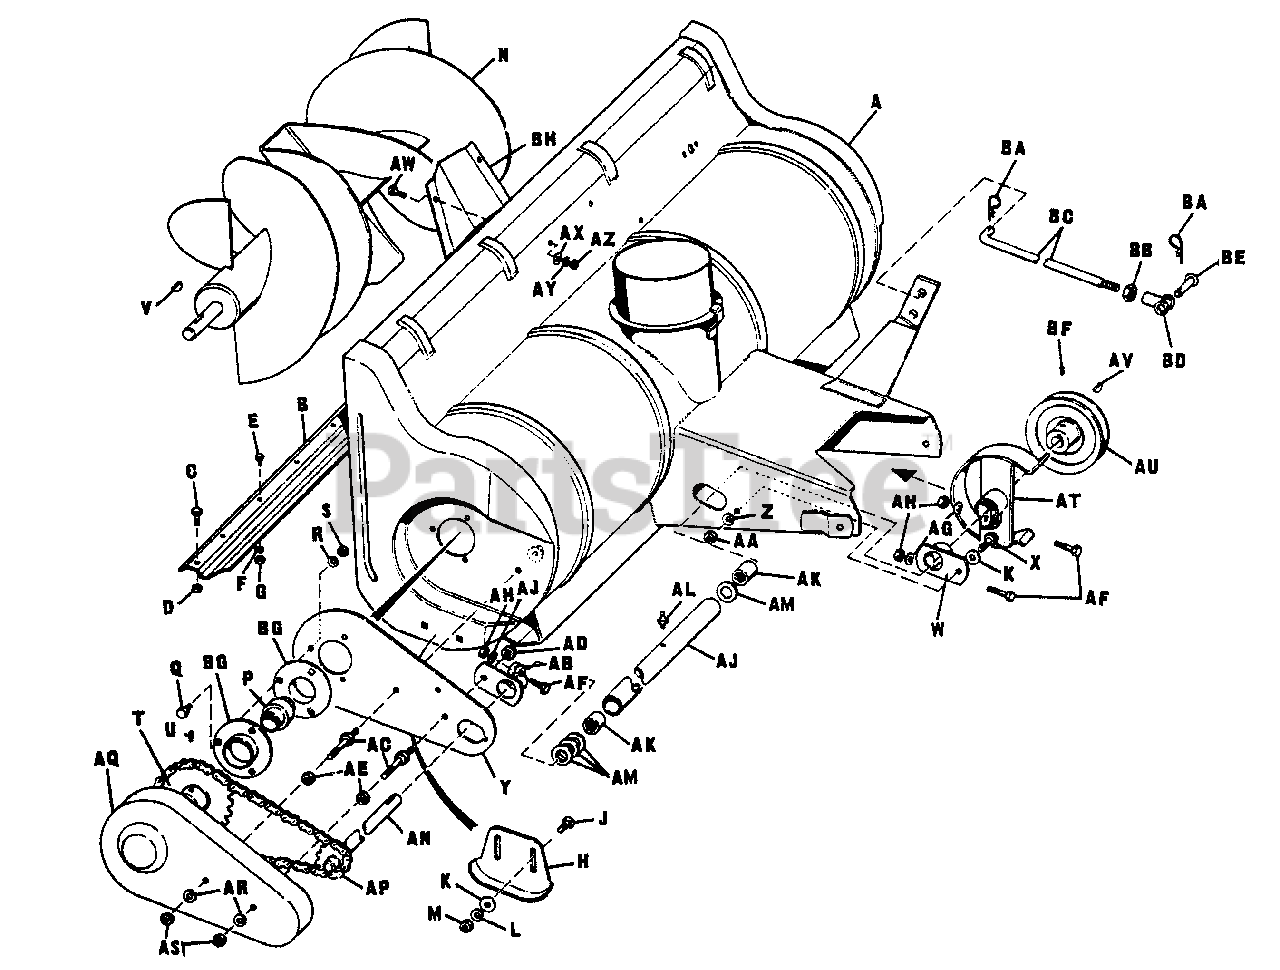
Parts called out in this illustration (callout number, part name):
A	Body Assembly
B	Body Scraper
C	Hex. Cap Screw,5/16"-18 x 5/8"
D	Full Lock Hex. Nut, 5/16"-18
E	Hex. Cap Screw, 1/4"-20 x 5/8"
F	Lock Washer, 1/4"
G	Full Hex. Nut, 1/4"-20
J	Carriage Bolt, 3/8"-16 x 3/4"
K	Plain Washer, 3/8"
L	Lock Washer, 3/8"
M	Full Hex. Nut, 3/8"-16
N	Rotor Assembly
P	Bearing Cartridge
Q	Hex. Cap Screw, 5/16"-18 x 3/4"
R	Lock Washer, 5/16"
S	Full Hex. Nut, 5/16"-18
T	Rotor Sprocket
U	Set Screw, 5/16"-18 x 5/16"
W	Support Assembly Clamp
X	Hex. Can Screw, 3/8"-1 x 1"
Y	Side Plate
Z	Lock Washer, 3/8"
AA	Full Hex. Nut 3/8"-16
AB	Support Assembly Clamp
AD	Nut, Flange, 3/8"-16
AE	Full Lock Hex., 3/8"-16
AF	Hex. Cap Screw, 5/16"-18 x 1-1/2"
AG	Lock Washer, 5/16"
AH	Full Hex. Nut, 5/16"-18
AJ	Bearing Housing
AK	Needle Bearing
AL	Grease Fitting
AN	Shaft Assembly
AQ	Chain Guard
AR	Lock Washer, 3/8"
AS	Full Hex. Nut, 3/8"-16
AT	Belt Guard Assembly
AV	Key, 3/16" Dia. x 3/4"
AW	Hex. Cap Screw, 5/16"-18 x 5/8"
AX	Plain Washer, 5/16"
AY	Lock Washer, 5/16"
AZ	Full Hex. Nut, 5/16"-18
BA	Spring Clip
BB	Full Hex. Nut, 1/2" x 20
BC	Front Lift Rod
BD	Adjusting End Yoke
BF	Set Screw 5/16"-18 x 5/16"
BG	Bearing Flange
